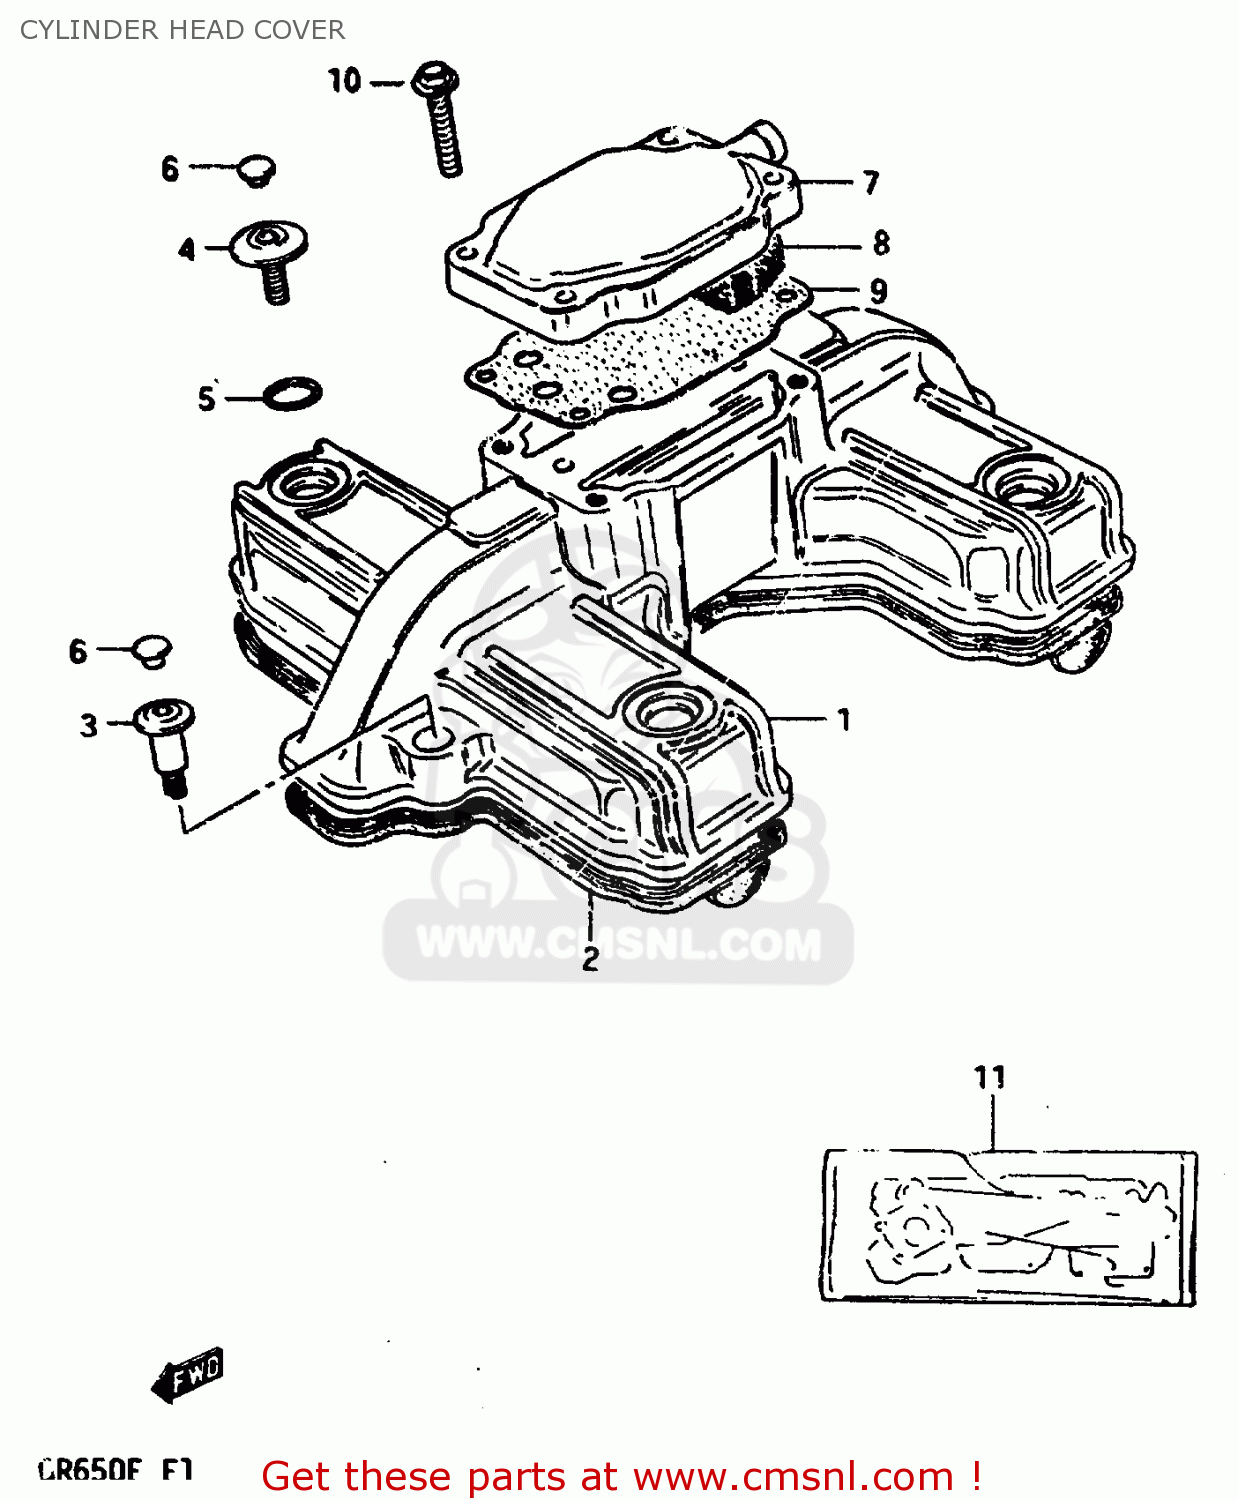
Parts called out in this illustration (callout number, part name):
1	COVER,CYLINDER HEAD
2	GASKET,CYLINDER HEAD COVER (NAS)
3	BOLT(7X19)
4	BOLT(7X5.5)
5	O RING(D:1.9,ID:14.5)
6	CAP(OD:10)
7	COVER,BREATHER
8	SEPARATOR,OIL BREATHER CO
9	GASKET (NAS)
10	BOLT
11	GASKET
